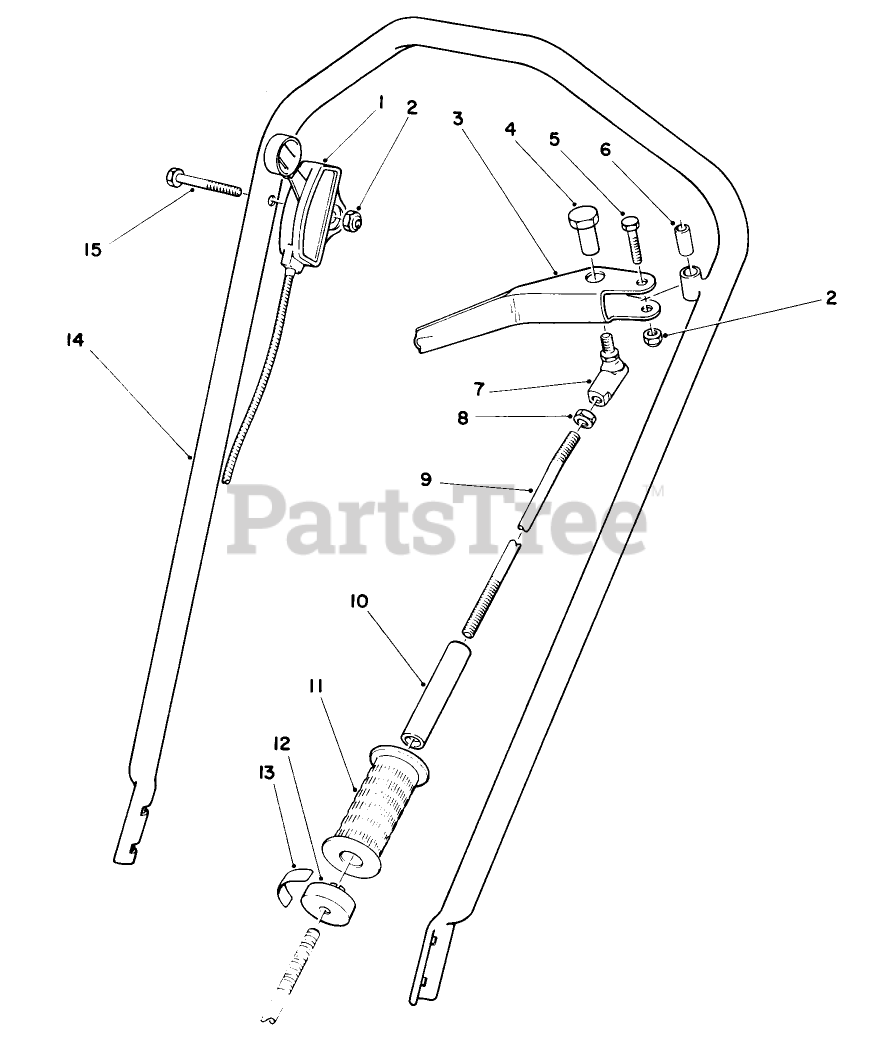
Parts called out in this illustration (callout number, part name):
2	NUT-LOCK, NI
5	SCREW-HH
7	BALL JOINT
8	NUT-HJ
15	SCREW-HH
